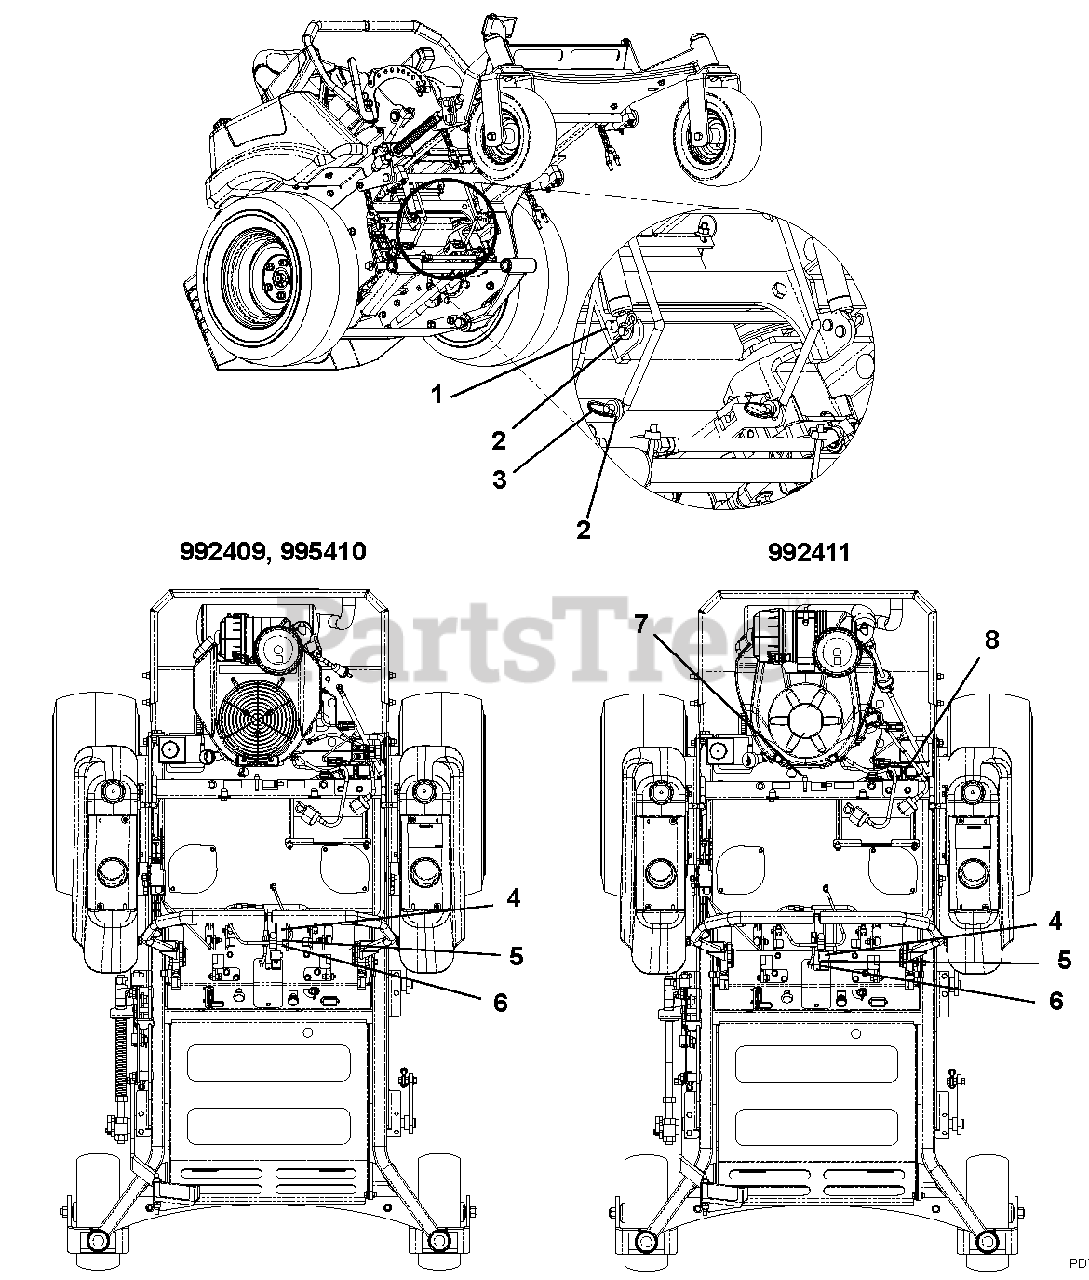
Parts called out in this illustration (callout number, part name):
1	PIN, HAIR .094 X 1.53 5/16-1/2 Y
2	WASHER, ISO8738, 10-160HV-ZN
3	RING, RETAINING
4	HARNESS, SEAT RELAY
5	SCREW, 12-24 SELF DRILLING
6	RELAY, ISO MINI ELEC.
7	CABLE TIE, .31 X 14.6 - BLACK
8	RELAY, SEALED W/ BRACKET
